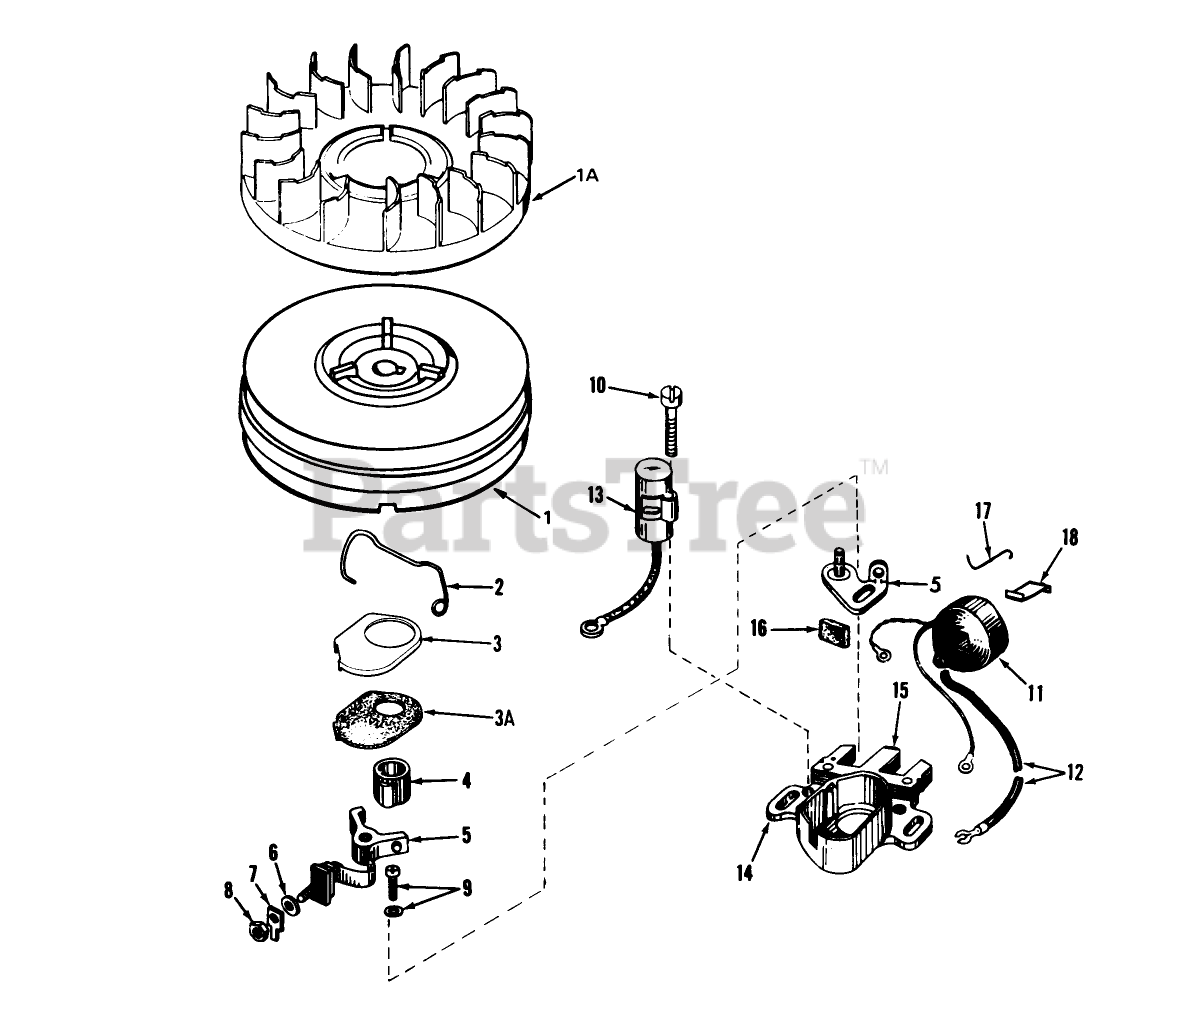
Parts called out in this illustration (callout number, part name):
1	Flywheel (Incl.Nos.1A, 3 3A)
2	Spring Breaker Box
3	Cover-Dust
3A	Gasket, Dust Cover
4	Cam, Breaker
5	Breaker Assy.
6	Washer
7	Terminal, Ground
8	DECAL
9	Breaker Screw
10	Condenser Screw
11	Coil Assy. (Incl. No. 12)
12	Wire, Lead
13	Condenser
14	Core Plate
15	Stator Assy. (Incl. Ref. #2 thru 11, 13, 14, 16, 17 19)
16	Felt,Cam Wiper
17	Clip, Coil
18	Spring Coil Wedge
